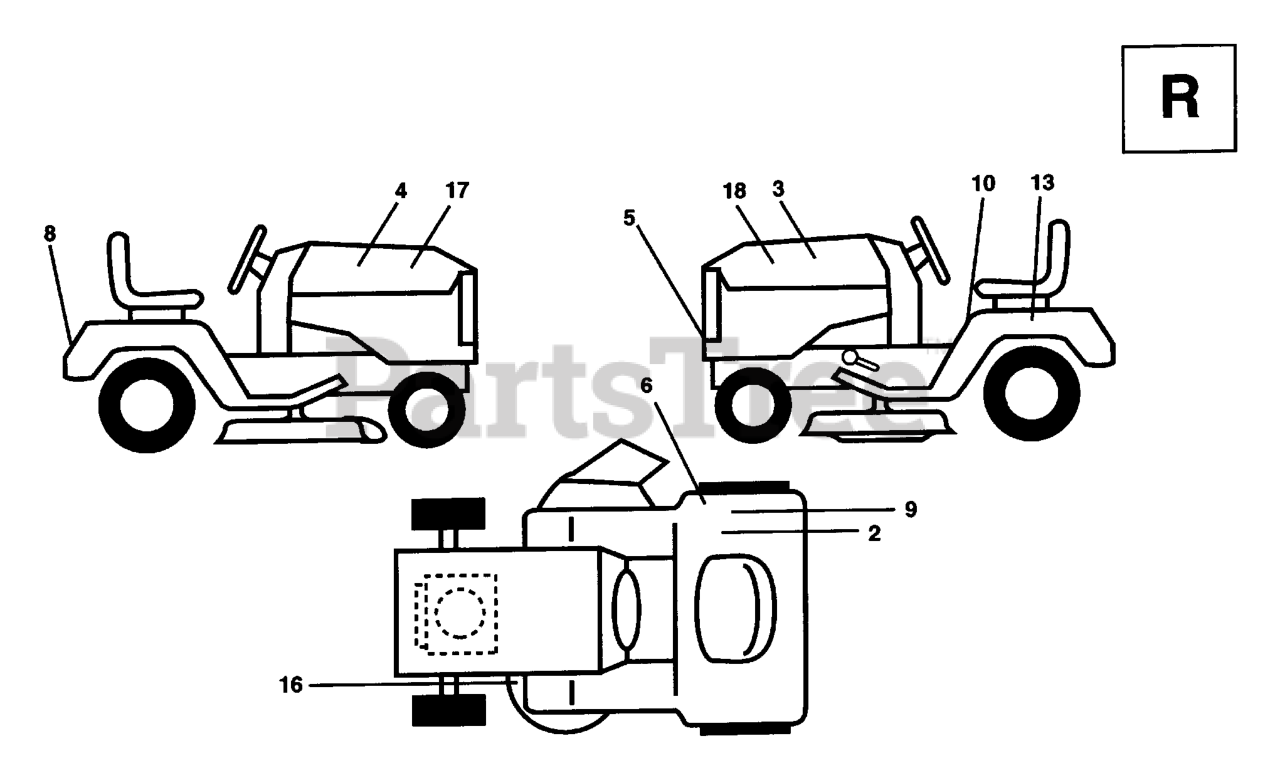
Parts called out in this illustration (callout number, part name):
2	DECAL CERTIFICATION
3	HOOD DECAL LH
4	HOOD DECAL RH
8	DECAL FENDER NLA
